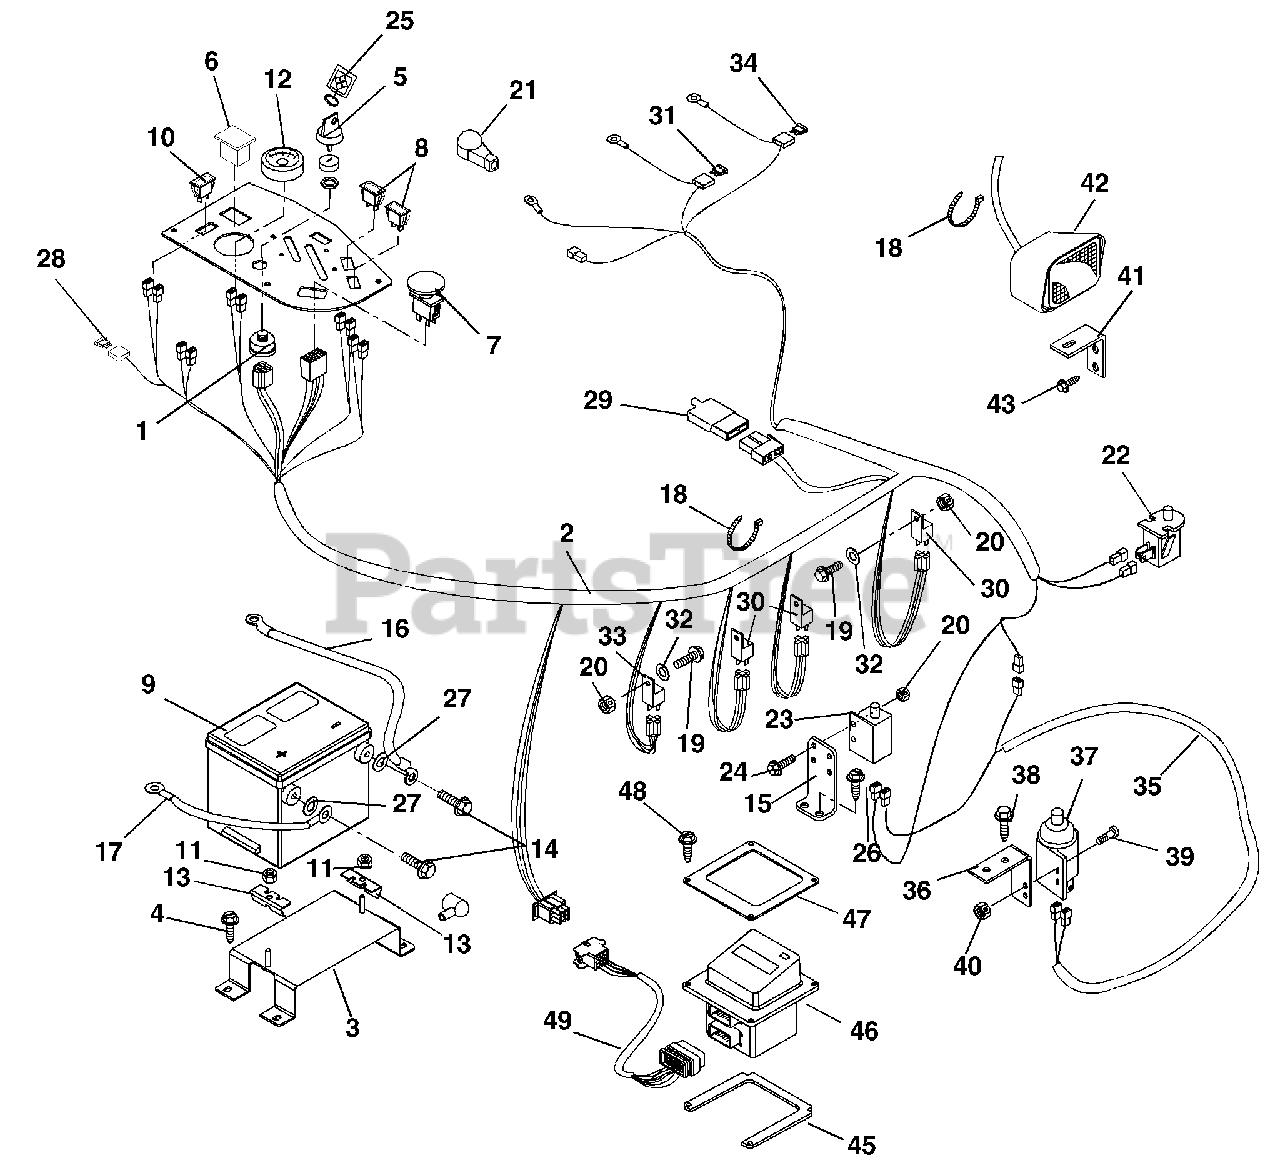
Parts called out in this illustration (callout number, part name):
1	Switch, Ignition (Diesel) (075, 076, 318, 319)
1	Switch, Ignition (073, 074)
2	Harness, Wiring (Diesel) (075, 076, 318, 319)
2	Harness, Wire (Gas) (073, 074)
3	Weldment, Battery Support
4	Screw-Tapping .38-16 x .75 Hex Washer Head
5	Key-with Cap
5	Ignition Key Set
7	Switch-Clutch With Retainer Ring
8	Light-Indicator Kit (075, 076, 318, 319)
8	Light-Indicator Kit (073, 074)
9	Battery with Tube
10	Switch, Light
11	Nut-Locking-Top-Flange .31-18
12	Gauge, Temperature
13	Bracket, Battery Hold-Down
14	Bolt-Hex .25-20 x .75 Grade 5
15	Mount, Safety Switch
16	Positive Cable (075, 076, 318, 319)
16	Positive Cable (073, 074)
17	Cable, Negative Battery (075, 076, 318, 319)
17	Ground Cable (073, 074)
18	Cable Tie
19	Screw-Machine 10-24 x .75 Hex Washer Head (075, 076, 318, 319)
19	Screw-Machine 10-24 x .75 Hex Washer Head (073, 074)
20	Nut-Locking-Nylon 10-24 With Insert (075, 076, 318, 319)
20	Nut-Locking-Nylon 10-24 With Insert (073, 074)
21	Battery Terminal Boot, Red
22	Switch, Snap Mounting (N.O.)
23	Switch-Single Pole
24	Screw-Machine 10-24 x .75 Hex Washer Head
25	Key Chain
26	Screw-Tapping .25-20 x .50 Hex Washer Head
27	Washer-Flat-Steel .406 x 1.00 x ..083
28	Fuse, 15 Amp
29	Diode, Connector Shell
30	Relay
31	Fuse, 30 Amp
32	Washer-Flat-Steel .25 x .562 x .049 (075, 076, 318, 319)
34	Fuse, 50 AMP (Maxi Fuse)
34	Fuse, 25 Amp
35	Harness, Wire Adapter CE (318, 319)
36	Mount- Switch (318, 319)
37	Switch-Single Pole (N.O.) with Cover (318, 319)
38	Screw-Tapping .31-18 x .50 Hex Washer Head (318, 319)
39	Screw-Machine 10-24 x .75 Hex Washer Head (318, 319)
40	Nut-Locking-Nylon 10-24 with Insert (318, 319)
41	Bracket, Headlight Mounting
42	Headlight
43	Screw-Tapping .38-16 x .50 Hex Washer Head
44	Boot, Eyelet Terminal
45	Spacer, Enclosure Mounting (Bottom)
46	Assembly, Eye-Q
47	Plate, Eye-Q Stiffener (Top)
48	Screw, Machine 10-24 x 1.0 Slotted Pan Black
49	Harness, Eye-Q
